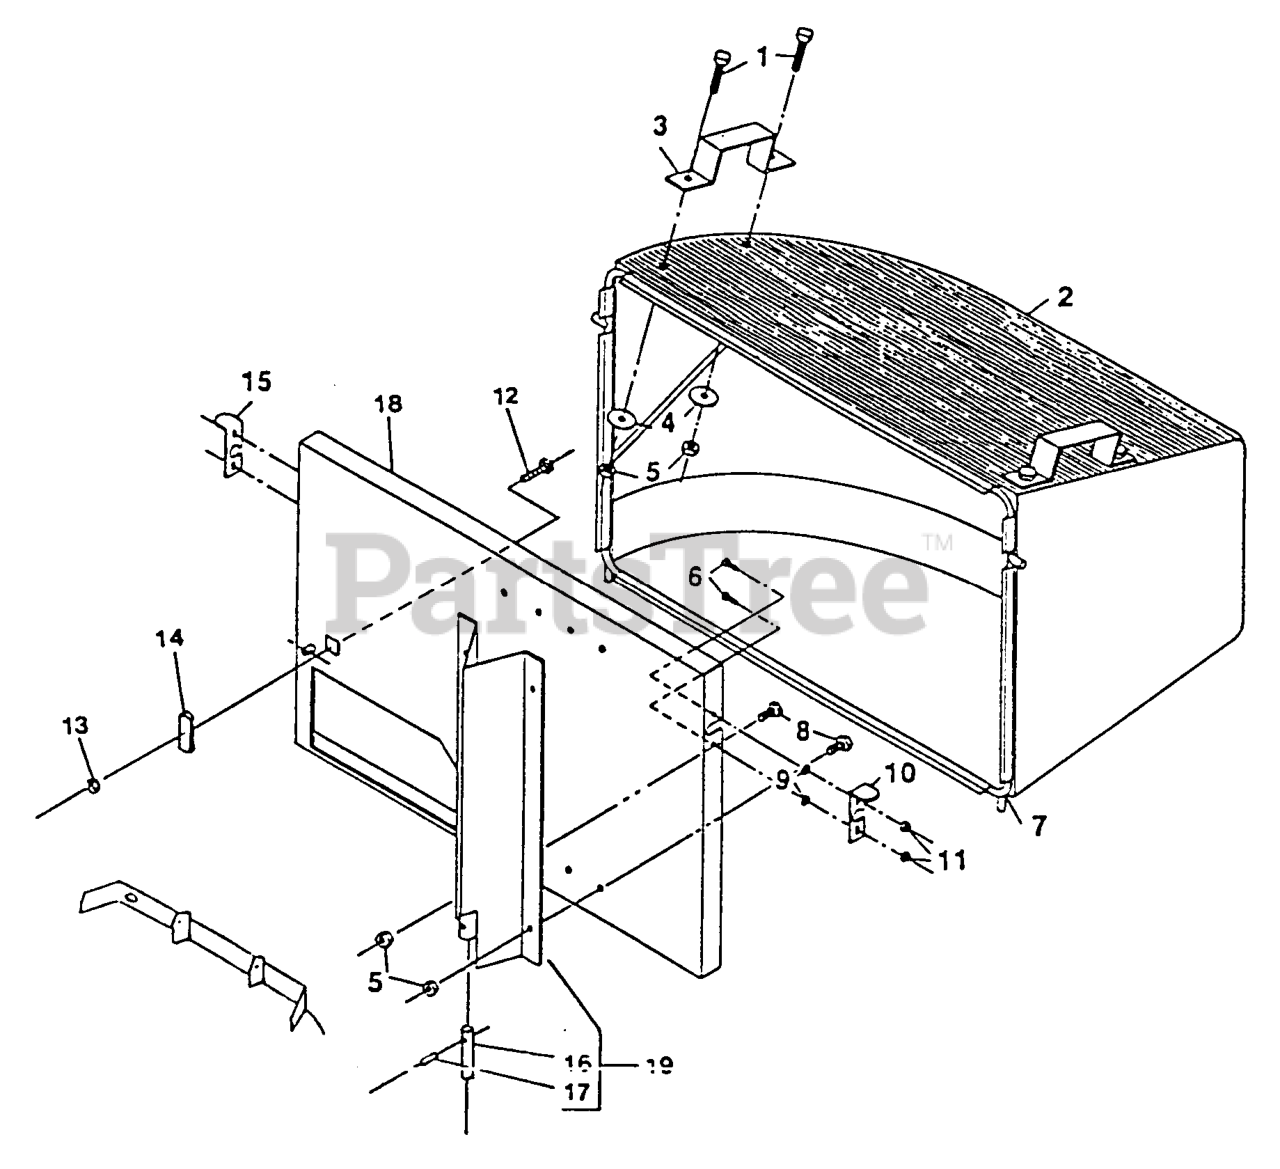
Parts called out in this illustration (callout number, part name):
7	FRAME-CATCHER
9	WASHER-SPRING
10	LATCH-CATCHER, RH
14	LATCH-CATCHER, GRASS
15	LATCH-CATCHER, LH
16	SHAFT-CATCHER, GRASS
17	PIN-ROLL
19	ASM,REAR CATCHER FRAME
